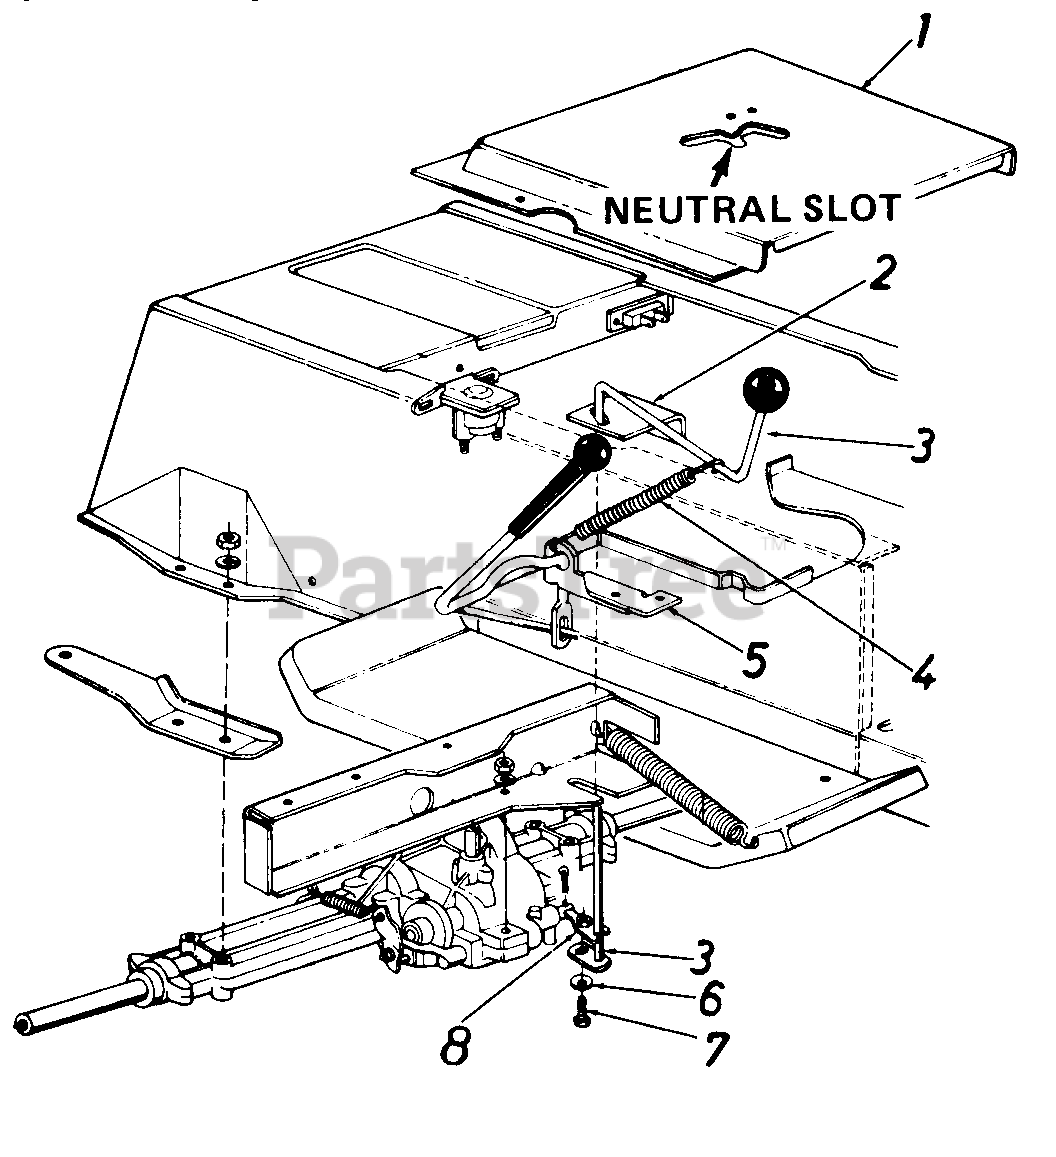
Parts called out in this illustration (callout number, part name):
1	Shift Cover
2	Shift Lever Bracket
3	Shift Lever Ass'y.
4	Extension Spring
5	Brake Lever Bracket
6	Belle-Wash. .25" I.D. x .75" O.D.
7	Hex Bolt 1/4-28 x .75" Lg.
8	Shift Lever Link Ass'y.
